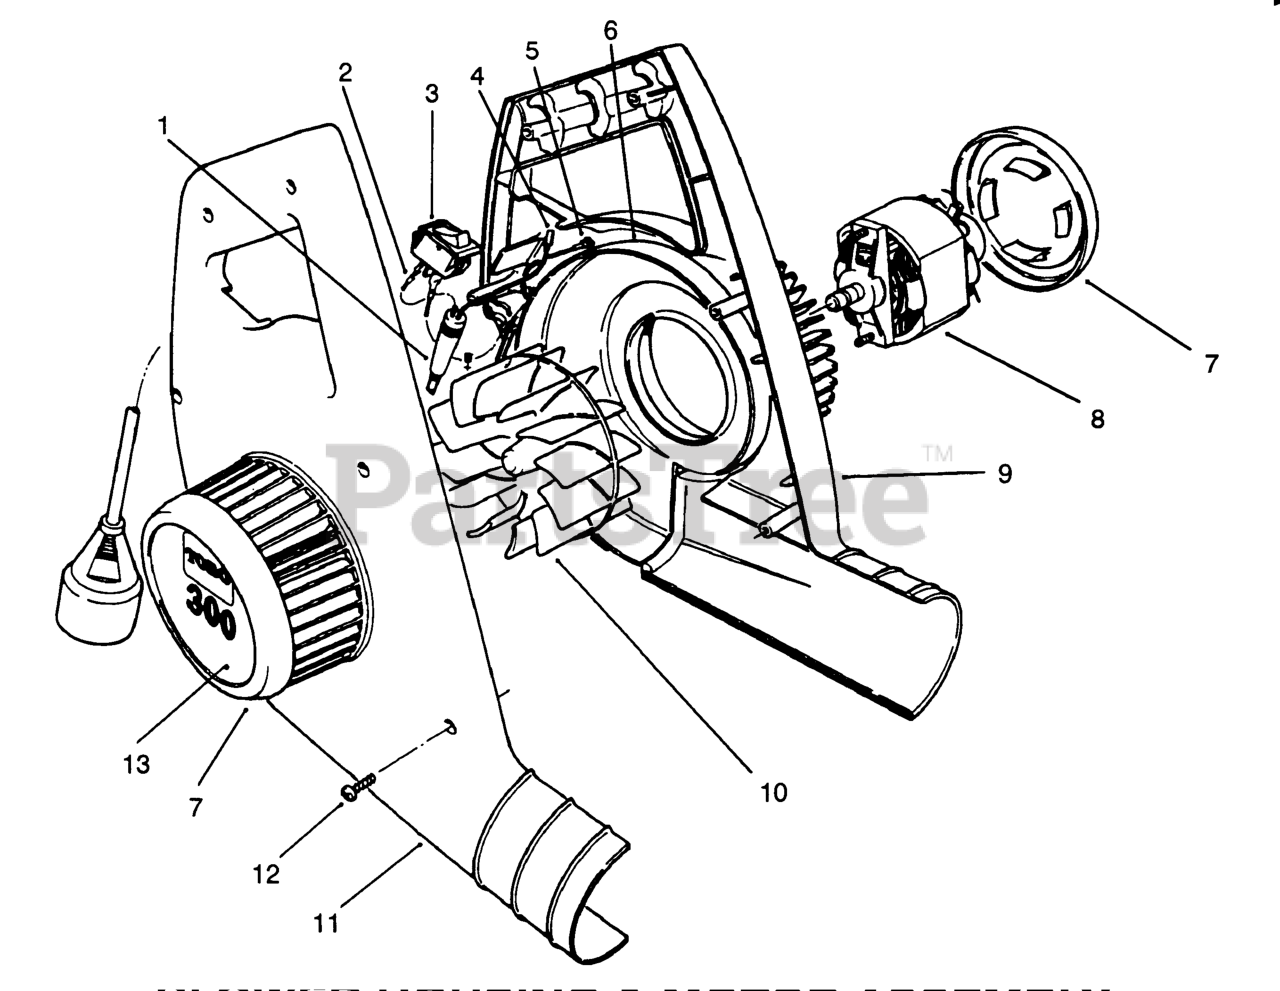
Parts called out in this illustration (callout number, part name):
1	POWER SUPPLY CORD
2	TERMINAL-1/4" PHOTOCELL
3	ROCKER SWITCH W/LETTERS
4	MALE COUPLER
5	FEMALE COUPLER
6	MOTOR CVR,300 BLWR(120V
7	MINI BV-INTAKE COVER
8	MOTOR, 120V MINI-BLOWER
9	Housing-L.H.
10	MINI BL-IMPELLER
11	HOUSING,RH,MINI-BLOWER
12	Screw
13	COVER - LABEL
